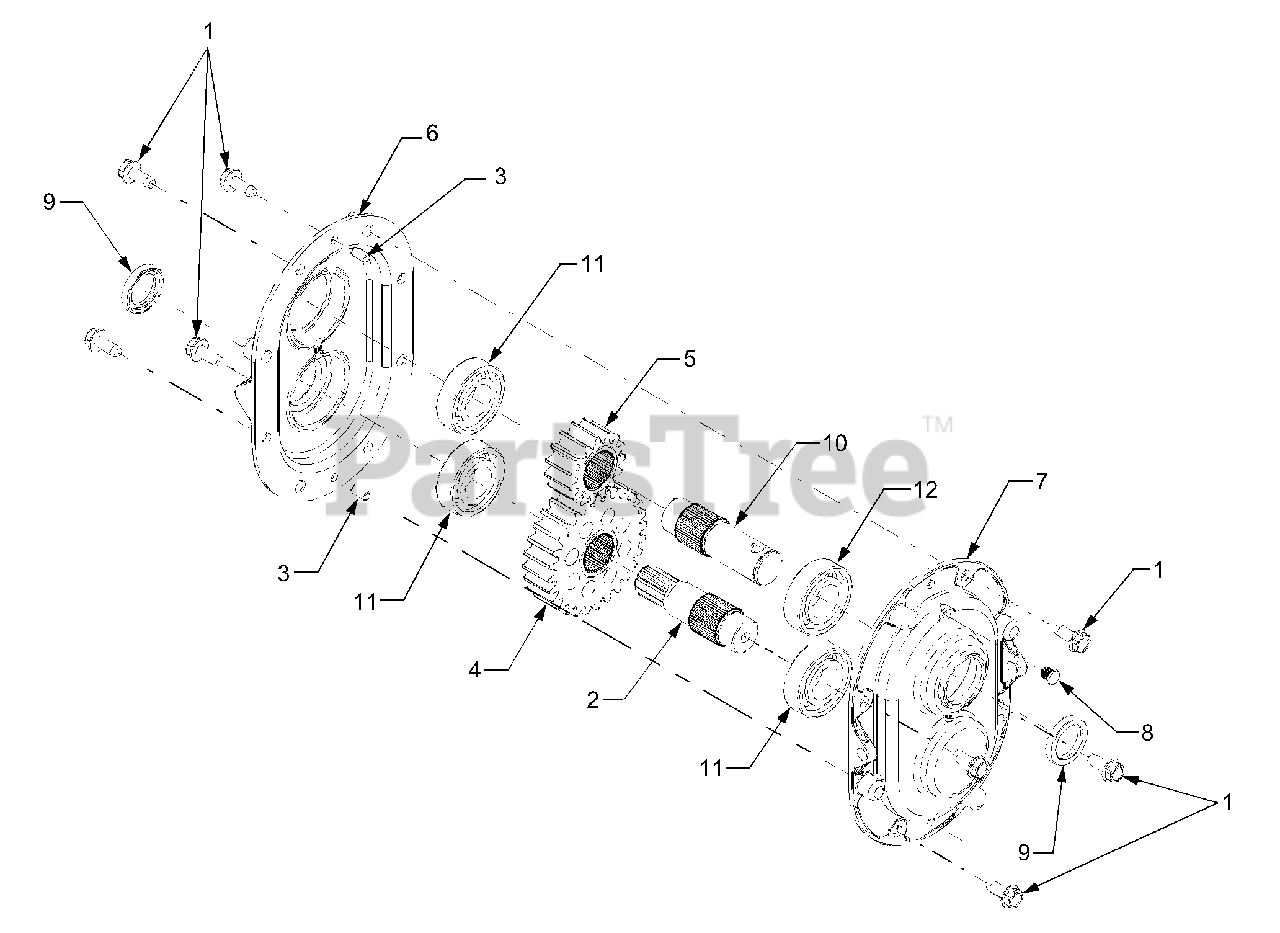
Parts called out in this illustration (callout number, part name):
1	Screw, Hex Wash. Hd. Tapp 5/16-18 x .75
2	Shaft, Output
3	Pin, Dowel, .25 x .5
4	Gear, Spur, 28T
5	Gear, Spur, 15T
6	Housing, Gear
7	Housing, Gear
8	Plug, 1/4 x .437
9	Seal, Oil
10	Shaft, Input
11	Bearing, Ball
12	Bearing, Ball
